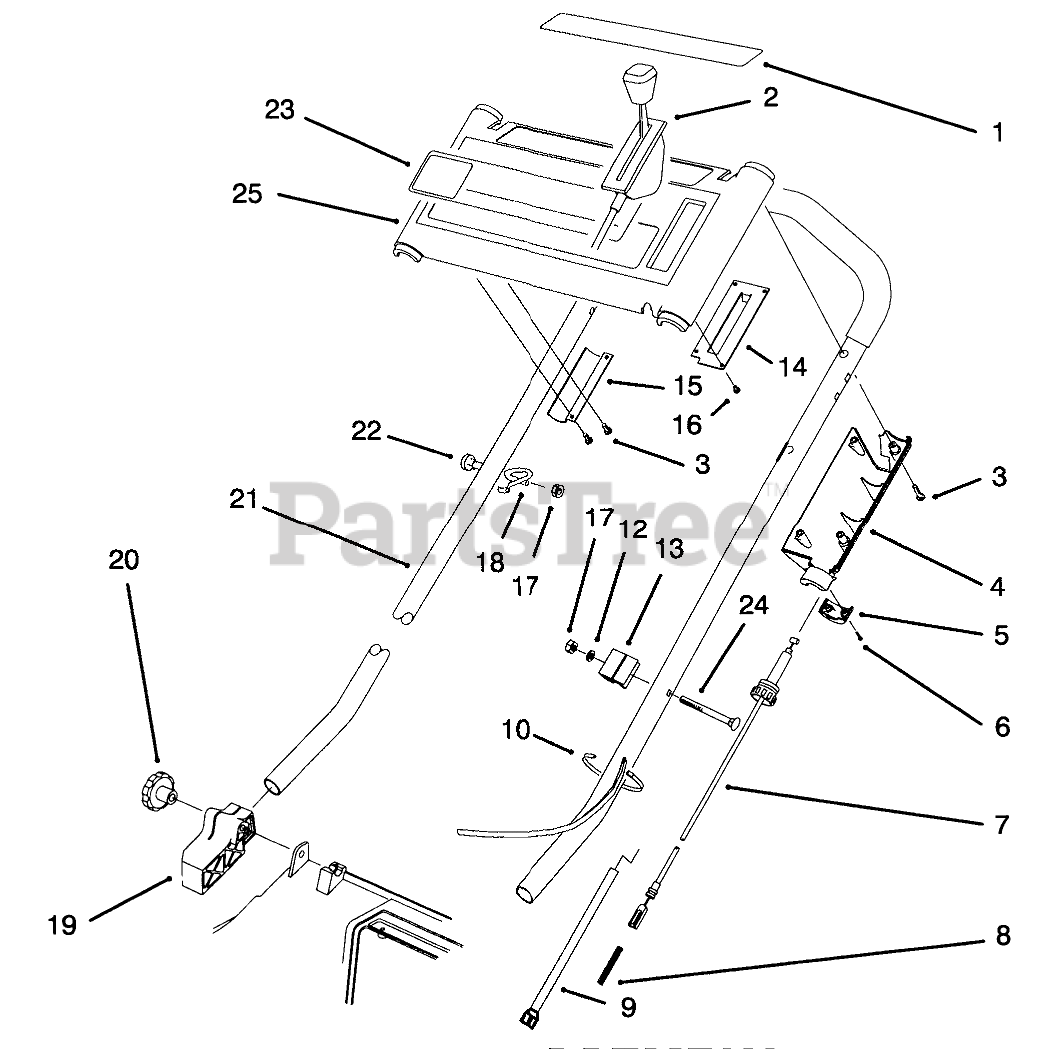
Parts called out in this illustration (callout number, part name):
1	DECAL - INSTRUCTION
2	CONTROL - THROTTLE
3	SCREW-PPH, PLASTITE
4	COVER-THROTTLE, LEVER
5	LOWER THROTTLE CAP
6	#4-14X.62 PLASTITE SCW
7	CABLE - TRACTION
8	SPRING-COMPRESSION
9	CABLE - BRAKE
10	TIE-CABLE
12	WASHER-FLAT
13	SUPPORT-CABLE
14	THROTTLE PLATE
15	Bracket-Panel
16	#6-19X.25 PLASK FORM SC
17	NUT-LOCK, NI
18	GUIDE-ROPE
19	MOUNT-HANDLE, RH
21	HANDLE (DIPPED)
22	Screw-Handle
23	DECAL - PANEL
24	SCREW-HANDLE
25	Panel-Control (Incl Ref.#1.&23)
